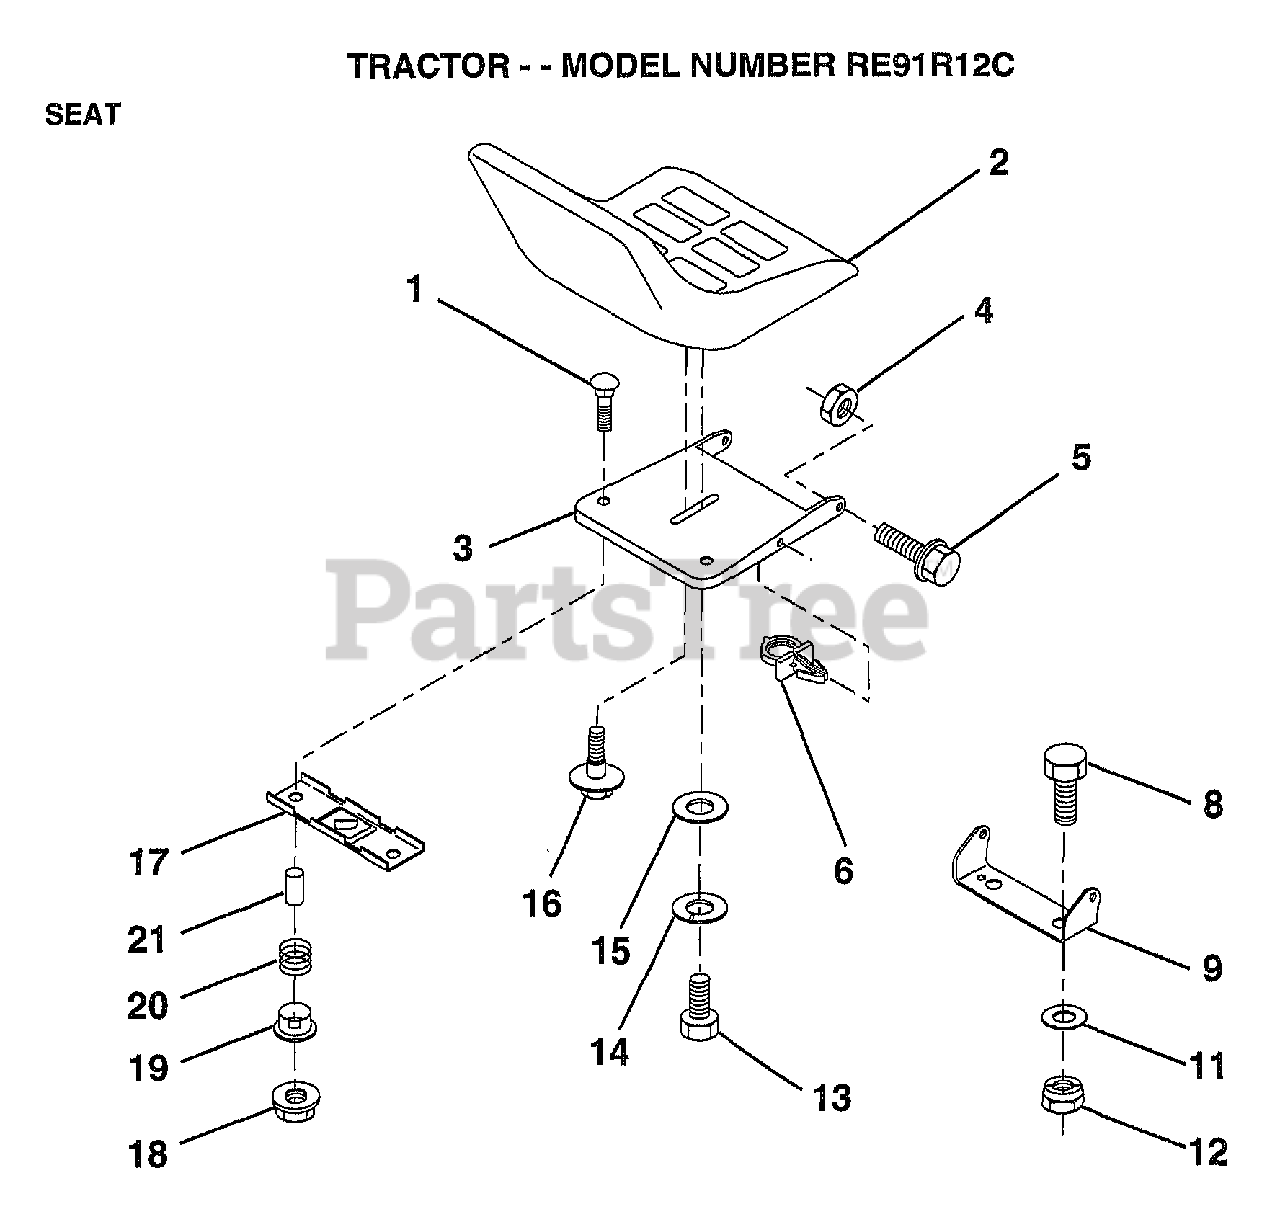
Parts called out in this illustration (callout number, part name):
1	BOLT-RD HD SQ NK
3	PAN-SEAT
4	NUT
5	"BOLT,SHOULDER"
6	CLIP.PUSH-IN.HING
8	BOLT
9	BRACKET PVT SEAT
11	WASHER
12	NUT
13	BOLT
14	LOCKWASHER
15	WASHER
16	"BOLT,SHOULDER"
17	BRKT SWITCH
19	BUSHING
20	SPRING
21	SPLIT SPACER
